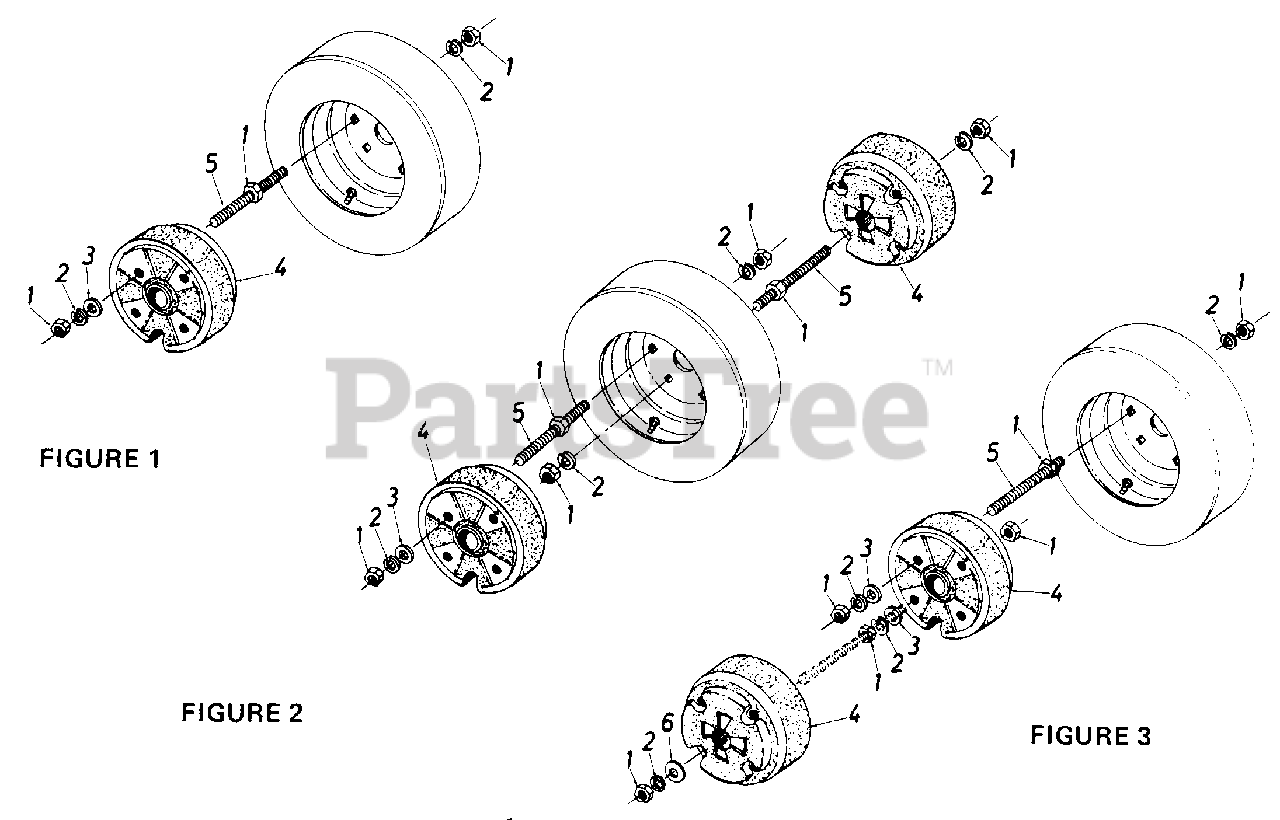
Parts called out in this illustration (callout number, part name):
1	Hex Nut 1/2-13 Thd.
2	Lock Washer 1/2" I.D.
3	Flat Washer.53" I.D. x.93" O.D.
4	Wheel Weight
5	Rod Threaded 1/2-13 x 9.50 Lg.
6	Fl.-Wash. .50" I.D. x 2.00" O.D.
